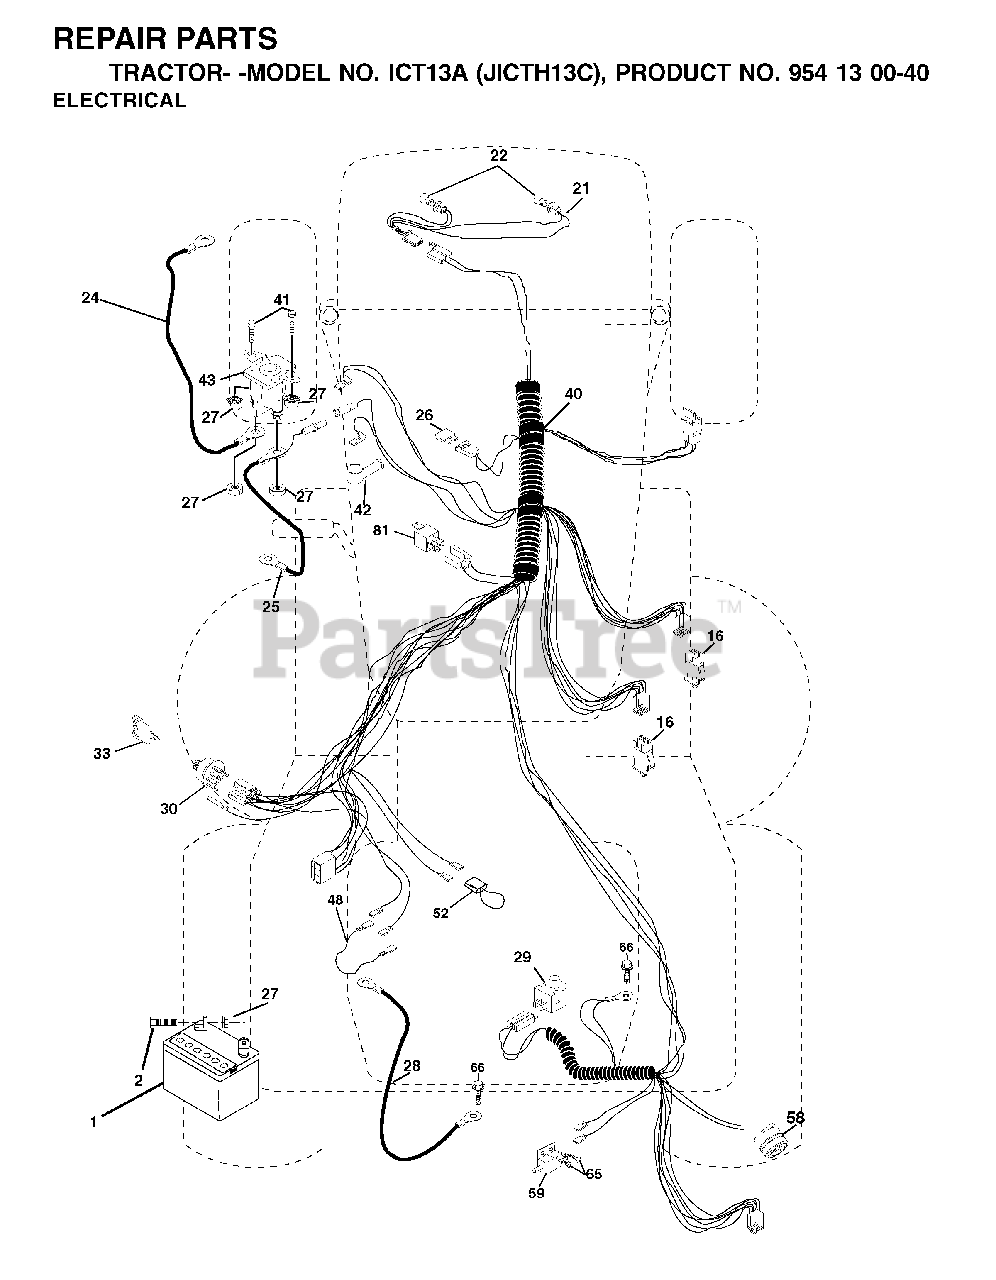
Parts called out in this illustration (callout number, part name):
1	BATTERY 12 VOLT 25 AMP
16	SWITCH INTERLOCK
21	HARNESS ASM, LIGHT W/4152J
22	LIGHTBULB
24	BATTERY CABLE GT
25	CABLE BATTERY
26	FUSE 15 AMP
27	NUT
28	CABLE GROUND
29	PLUNGER SWITCH (COLOR:OLIVE)
30	IGNITION SWITCH
33	KEY MLD GEN DELTA
42	TERMINAL COVER
43	REPL BY 532 1461-54
52	WIRE PROTECTION LOOP
58	BUZZER
81	RELAY.ASSY.T
